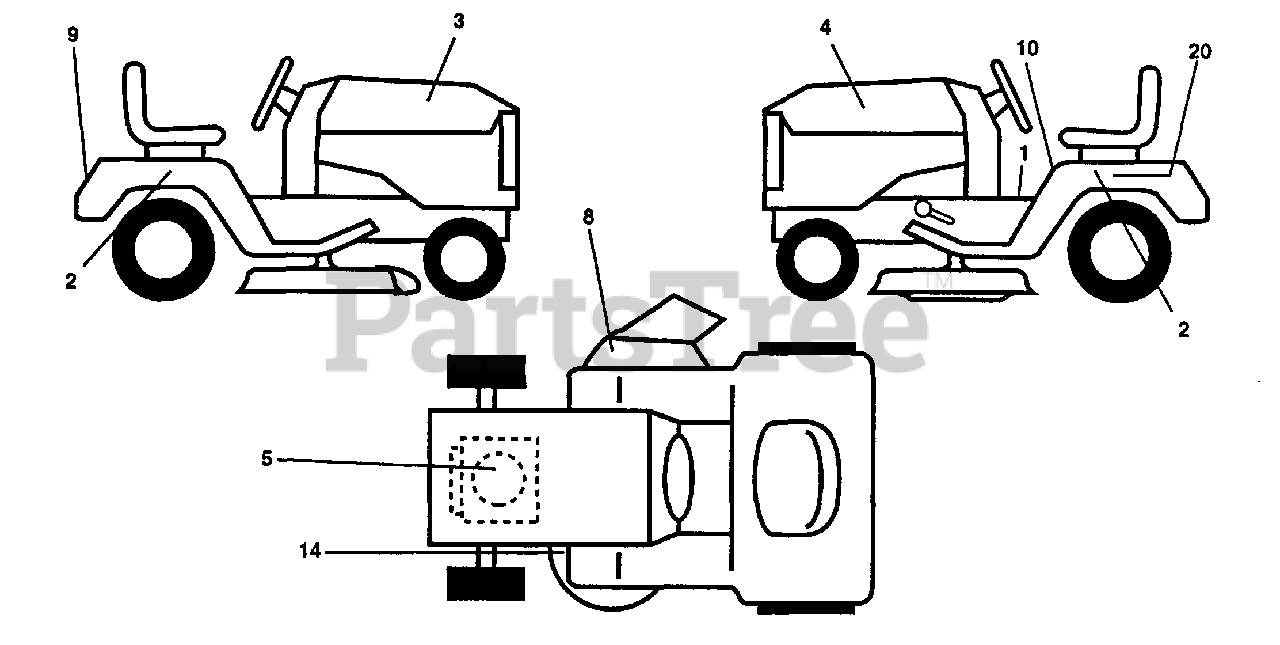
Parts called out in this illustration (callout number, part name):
1	Decal Oper Step Thru Eng/Fr
2	Decal Fender Auto Husq. Radius
3	Decal Hood RH
4	Decal Hood LH
5	Decal HP Engine
8	Decal Warning
9	Decal Fender Husq
10	Decal Fender Danger Eng/Fr
14	Decal V-Belt Schematic
20	Decal Bat Dan/Psn
